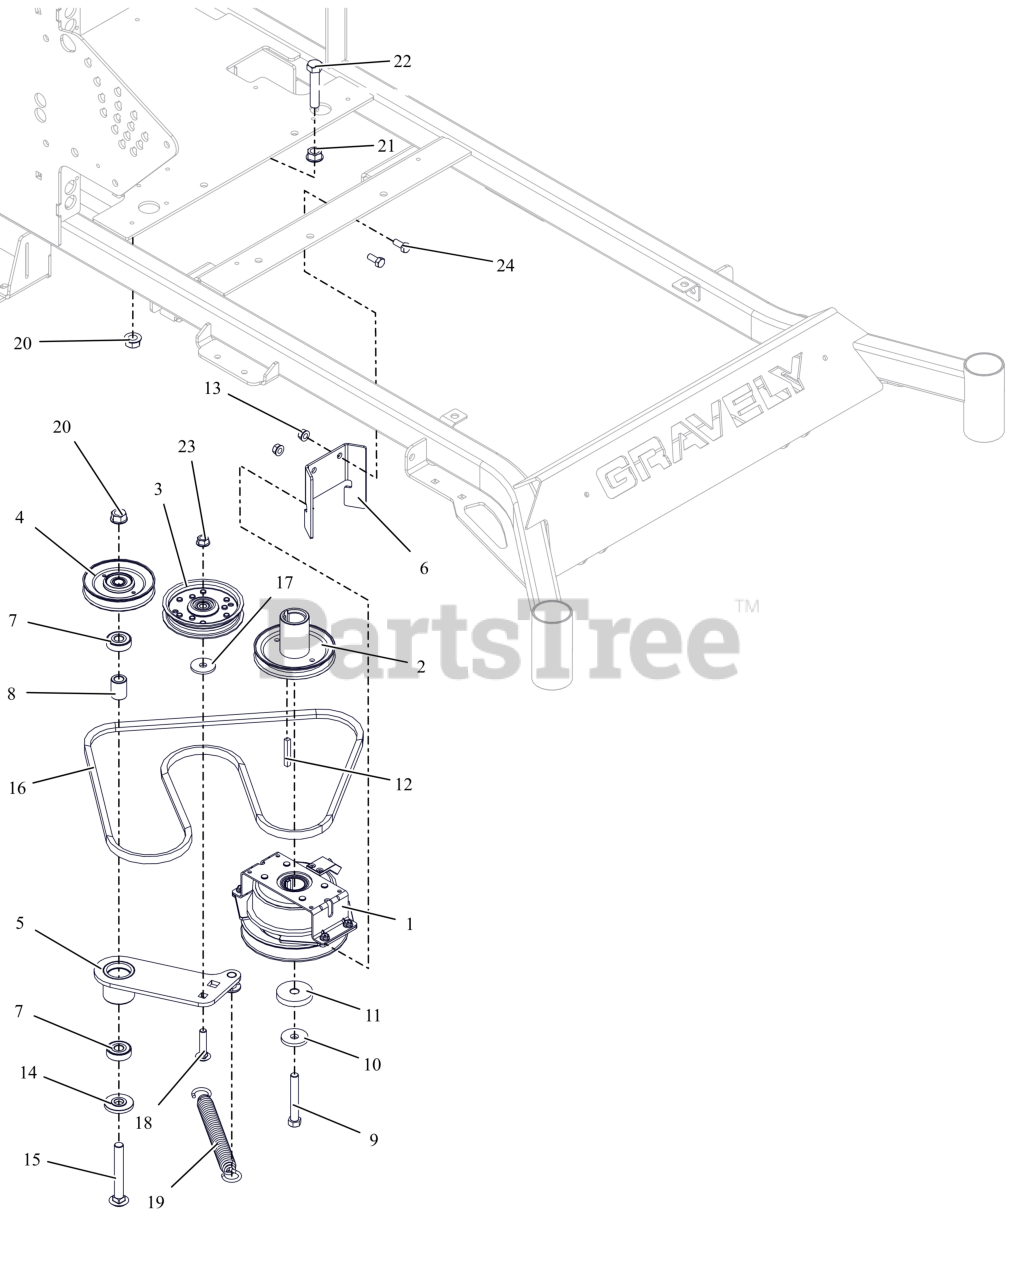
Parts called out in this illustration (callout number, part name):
1	CLUTCH, OGURA GT1.5-AR11(D)
2	SHEAVE, ENGINE 4.50 X 1.127
3	ASM, 4" IDLER (.75 WIDE)
4	SHV, .50"ID X 4.00"OD V-IDLER
5	WMT- HYDRO IDLER ARM
6	BRKT- CLUTCH STOP (RED)
7	BRG-BALL .500X1.38X.437
8	SPACER .510 X .867 X 1.1485
9	BLT, HEX 0.4375-20X3 G8 ZCC NT
10	WASHER, 7/16" SPRING DISK
11	SPACER, .474/.459X2.00X.350
12	KEY-STR .25X1.75X.25
13	NUT,LK-CTR-FLG .31-18 GF ZCC
14	SPACER, IDLER ARM
15	BTL,RHSN .500-13 X 3.75 G5 ZCC
16	BELT- A SECTION
17	WSHR,FLT .406X1.375X.135 ZCC
18	BLT, RHSN .38-16X1.75 G5 ZCC
19	SPRING- EXTENSION
20	NUT-LK-CTR-FLG .500-13 GG ZCC
21	NUT, SPNLK-FLG .50-13 G5 ZCC
22	BLT, HEX .50-13X2.50 G5 ZCC
23	NUT-LK-CTR-FLG .375-16 GF ZCC
24	BLT,HEX .31-18X.75 G5 ZCC
